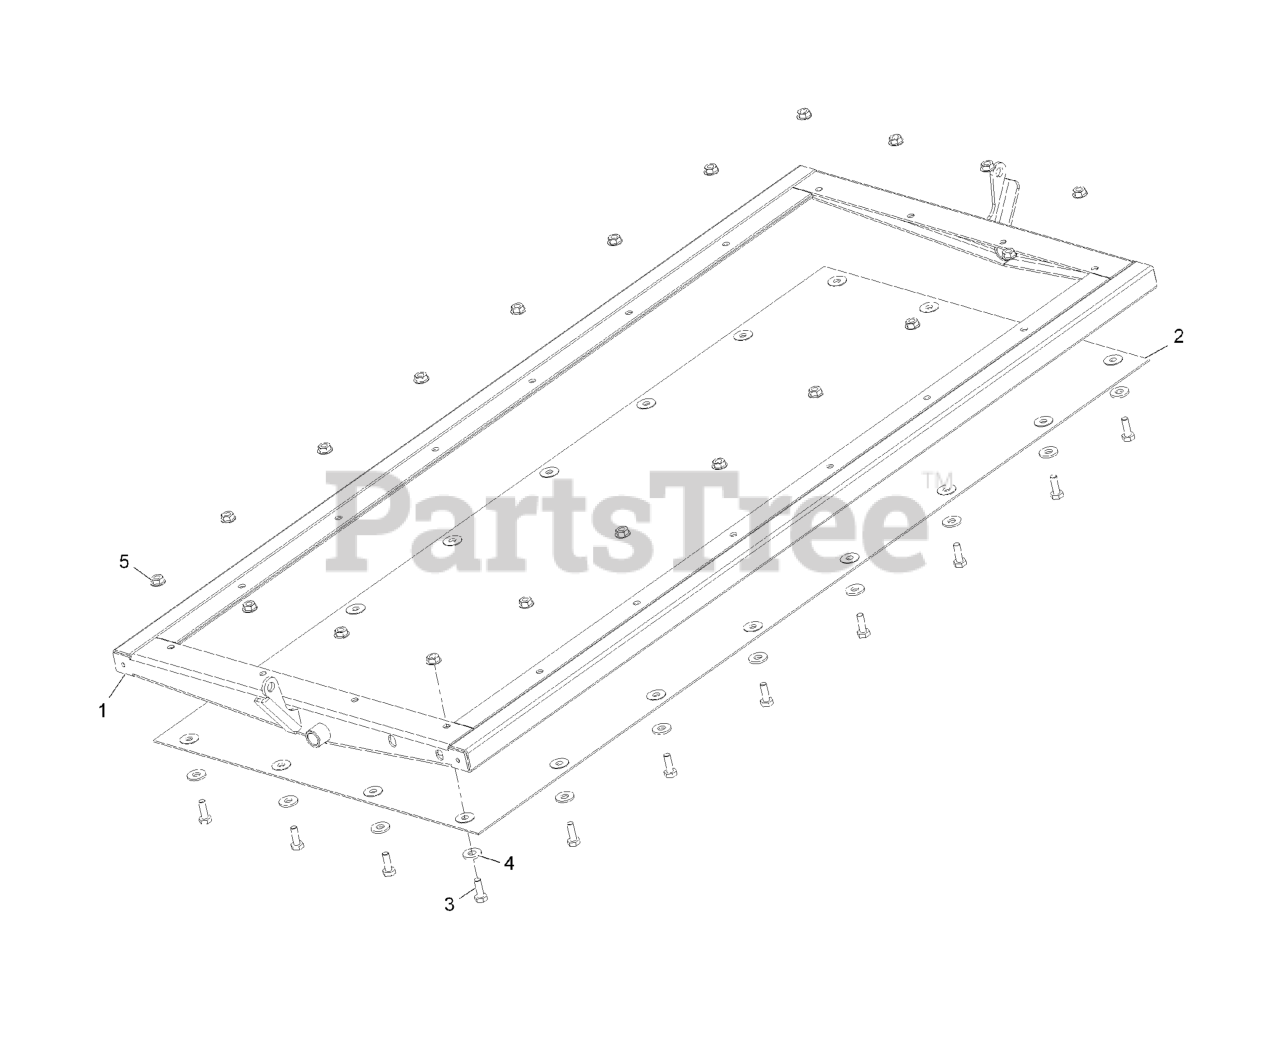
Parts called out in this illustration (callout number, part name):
1	DOOR-FRAME
2	SCREEN-DOOR
3	SCREW-HH
4	WASHER-FLAT
